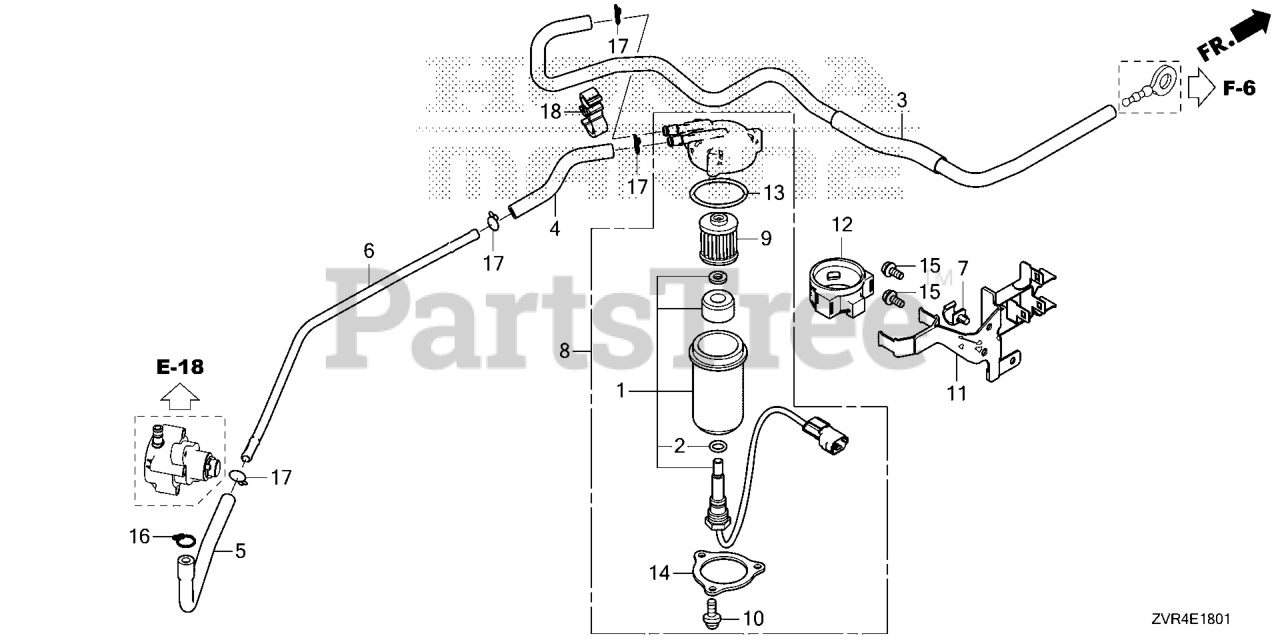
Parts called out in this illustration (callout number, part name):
1	CUP SET, WATER SEPARATOR
3	TUBE COMP A, FUEL
4	TUBE B, FUEL
5	TUBE C, FUEL
6	PIPE, FUEL
7	CLAMP B, FUEL TUBE
8	FILTER ASSY., FUEL (LOW)
9	FILTER, FUEL
10	SCREW, PAN (5X12)
11	STAY COMP A
12	SUSPENSION, STRAINER
15	BOLT, FLANGE (6X14)
16	CLIP, TUBE (B1 14.5)
17	CLIP, TUBE (B12)
18	CLAMP, CONDENSER PIPE
